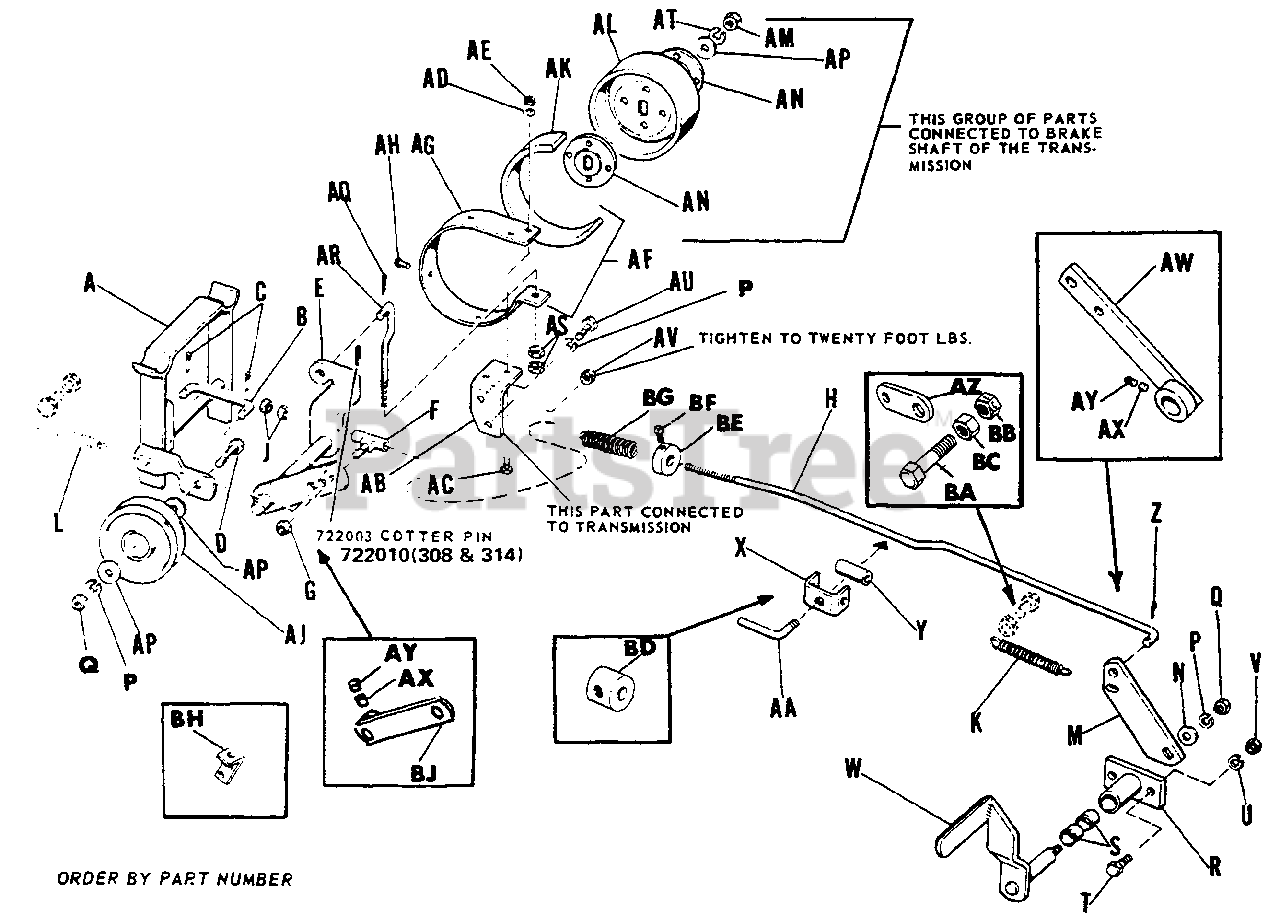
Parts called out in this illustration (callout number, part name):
A	Support Assembly-Seat
B	Clutch Lever Link
C	Cotter Pin
D	Hex. Cap Screw
E	Lever Assembly-Pivot (154111)*
F	Guide Assembly-Rod
G	Full Lock Hex. Nut
H	Brake & Clutch Rod (157040)*
J	Full Hex. Nut
K	Tension Spring (154369)*
L	Tension Spring (157041)*
M	Pedal Foot Arm
N	Plain Washer
P	Lock Washer
Q	Full Hex. Nut
R	Foot Pedal Bearing Ass'y
T	Hex. Cap Screw
U	Lock Washer
V	Full Hex Nut
W	Foot Pedal Assembly (157043)*
X	Bracket Assembly Assembly
Z	Cotter Pin (72009)*
AA	Park Brake Lock
AB	Brake Band Bracket
AC	Hex. CapScrew, 1/4"-20 x 3/4"
AD	Lock Washer, 1/4"
AE	Full Hex. Nut, 1/4"-20
AF	Brake Band & Lining Assembly (154132)*
AG	Brake Band (154060)*
AH	Rivet #7 x 5/16"
AJ	Idler Pulley
AK	Brake Lining
AL	Brake Drum (154131)*
AM	Full Hex. Nut, 7/16"-14
AN	Special Washer
AP	Plain Washer
AQ	Cotter Pin
AR	Brake Rod
AS	Full Hex. Nut, 3/8"-16
AT	Lock Washer 7/16"
AU	Hex. Cap. Screw,
AW	Foot Pedal Lever Assy.
AX	Screw, Set, Sock. Hd., Cup Pt. 5/16"-18 x 1/4"
AV	Full Hex. Nut. 3/8"-16
AZ	Spring Holder
BA	Hex Cap Screw, 5/16"-18 x 1-1/4"
BB	Full Lock Hex Nut, 5/16"-18
BC	Full Hex Nut, 5/16"-18
BD	Parking Brake Collar
BF	Screw, Set, Sq. Hd., 1/4"-20 x 3/8"
BG	Compression Spring
BH	spring Retainer
BJ	Clutch & Brake Lever Assy.
